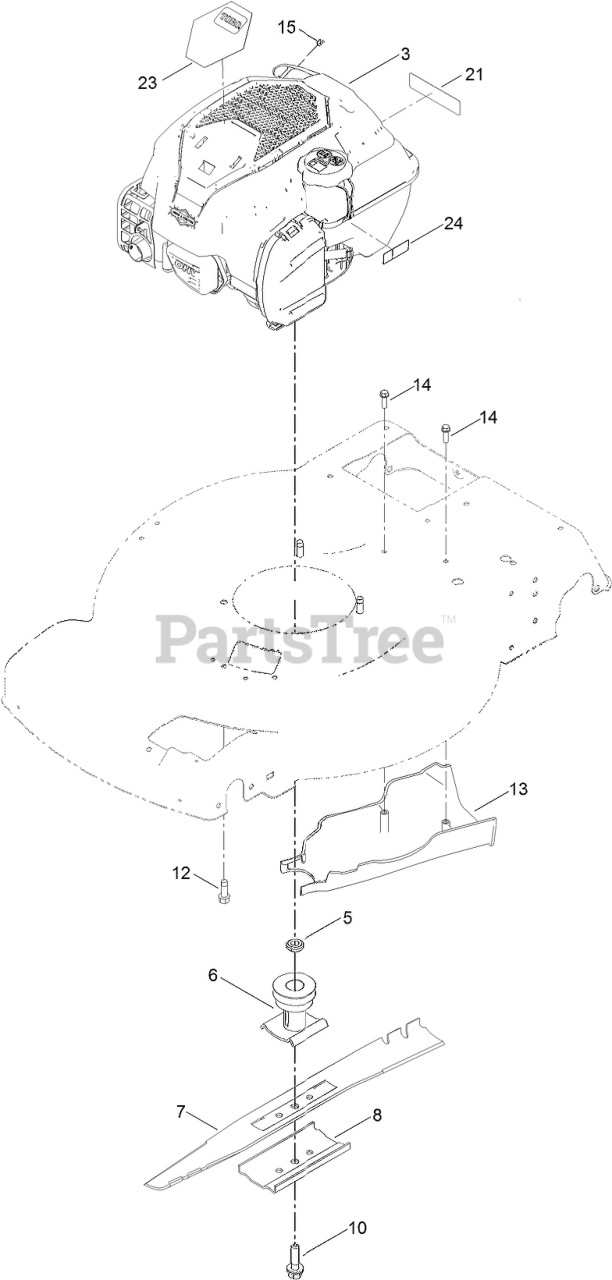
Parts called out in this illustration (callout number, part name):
5	SPACER-DRIVER
6	DRIVER-BLADE
7	BLADE-22 INCH
8	SUPPORT-BLADE
10	BOLT-BLADE
12	SCREW-TAPTITE
13	COVER-BELT, REAR
14	SCREW-HWH
15	STOP-ROPE
21	DECAL-ARRESTOR, SPARK
23	DECAL- B&S SHROUD
24	DECAL-LEVEL, FUEL
